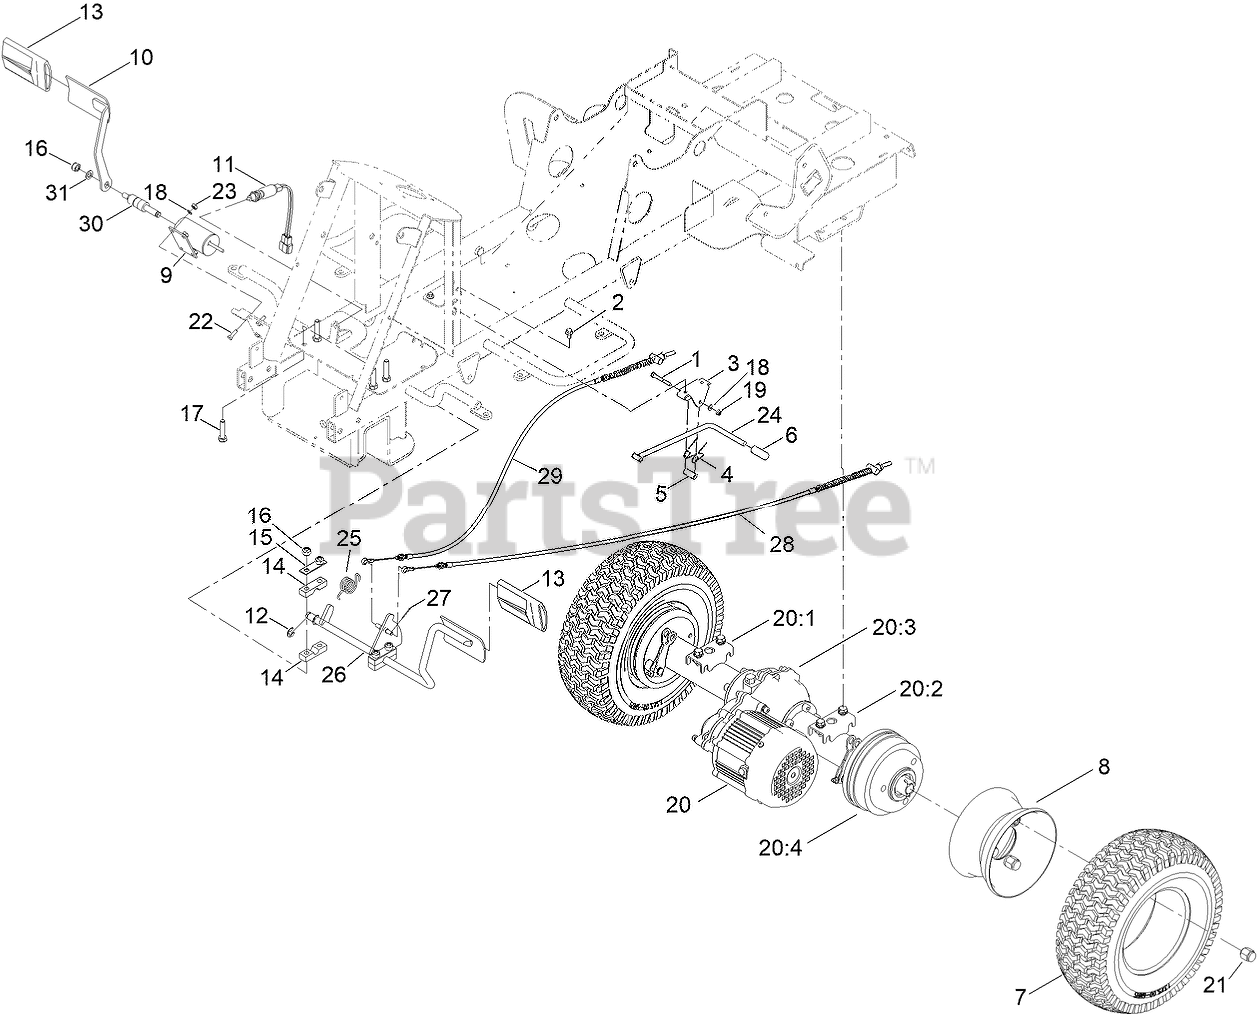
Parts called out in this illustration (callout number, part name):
3	BRACKET, PARKING BRAKE
4	SPRING, PARKING BRAKE
5	BUSH, PARKING BRAKE
6	HANDLE, PARKING BRAKE
7	TYRE, WHEEL
8	HUB, REAR WHEEL
9	HUB ASM, THROTTLE
10	PEDAL, LEFT
11	BRAKING SWITCH ASM
12	CLIP, PEDAL HOLDER
13	COVER, PEDAL
14	BLOCK, PEDAL HOLDER
15	PLATE, PEDAL MOUTING
16	NUT-HEX, NI
17	BOLT
18	WASHER
19	NUT-NYLOC
20	TRANSMISSION ASSEMBLY
20:1	SEMI AXLE ASM
20:2	SEMI AXLE ASM
20:3	REDUCTION GEARBOX ASM
20:4	REAR MOTOR ASM
22	SCREW-HH
24	LEVER, HAND BRAKE
25	SPRING, PEDAL
26	PEDAL, BRAKE
27	BOBBY PIN
28	CABLE, BRAKE (LH)
29	CABLE, BRAKE (RH)
30	SHAFT, THROTTLE
31	WASHER
